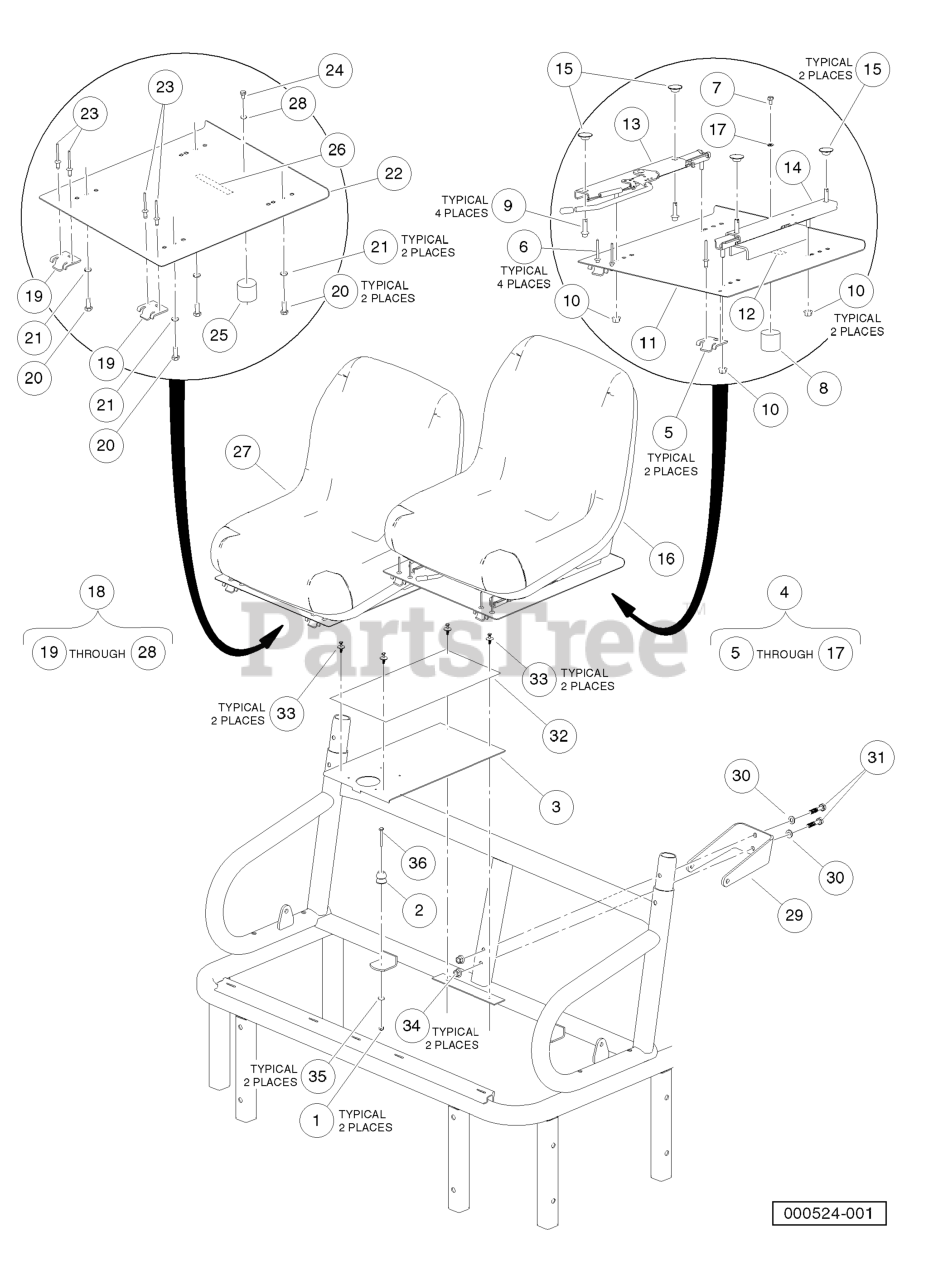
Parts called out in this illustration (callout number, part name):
1	LOCKNUT, M6-1.00 NYLON INSERT
2	SEAT HOLDER BASE
3	PAN, CENTER, CLOSEOUT
4	ASM, BUCKET SEAT ADJUSTABLE
5	HINGE PLATE
6	RIVET, 1/4 X .438 BLIND
7	SCREW, 6M-1.00 X 10MM HEX HEAD
8	SEAT HOLDER CUP
9	BOLT - FLANGED HD, M8 X 30.0
10	NUT FLG, M8 X 1.25 MECH DEF
11	PAN, SEAT, DRIVER ASM
12	DECAL, WARNING HOT SURFACE
13	ADJUSTER, FORE/AFT
14	ADJUSTER, SLIDER
15	WASHER, BELL
16	SEAT, BUCKET, GRAY
17	LOCKWASHER, 1/4 HELICAL SPLIT
18	Assembly, Bucket Seat w/Spacers
19	HINGE PLATE
20	SCREW, M8-125 X 22 HEX GR.8.8
22	PAN, SEAT - PASSENGER
23	RIVET, 1/4 X .438 BLIND
24	SCREW, 6M-1.00 X 10MM HEX HEAD
25	SEAT HOLDER CUP
26	DECAL, WARNING HOT SURFACE
27	SEAT, BUCKET, GRAY
28	LOCKWASHER, 1/4 HELICAL SPLIT
29	BRKT, SEATBELT, BOLT-ON
30	WASHER, HARD, M10, ZN-NI/BLK
31	BOLT, M10 X 45, ZN-NI/BLK
32	COVER, CENTER CONSOLE
33	SCREW, TUFLOK PANEL, 1/4
34	NUT, FLANGED, M10 X 1.5, BLACK
35	WASHER 1/4 FLAT
36	BOLT, M6 X 1 X 45
